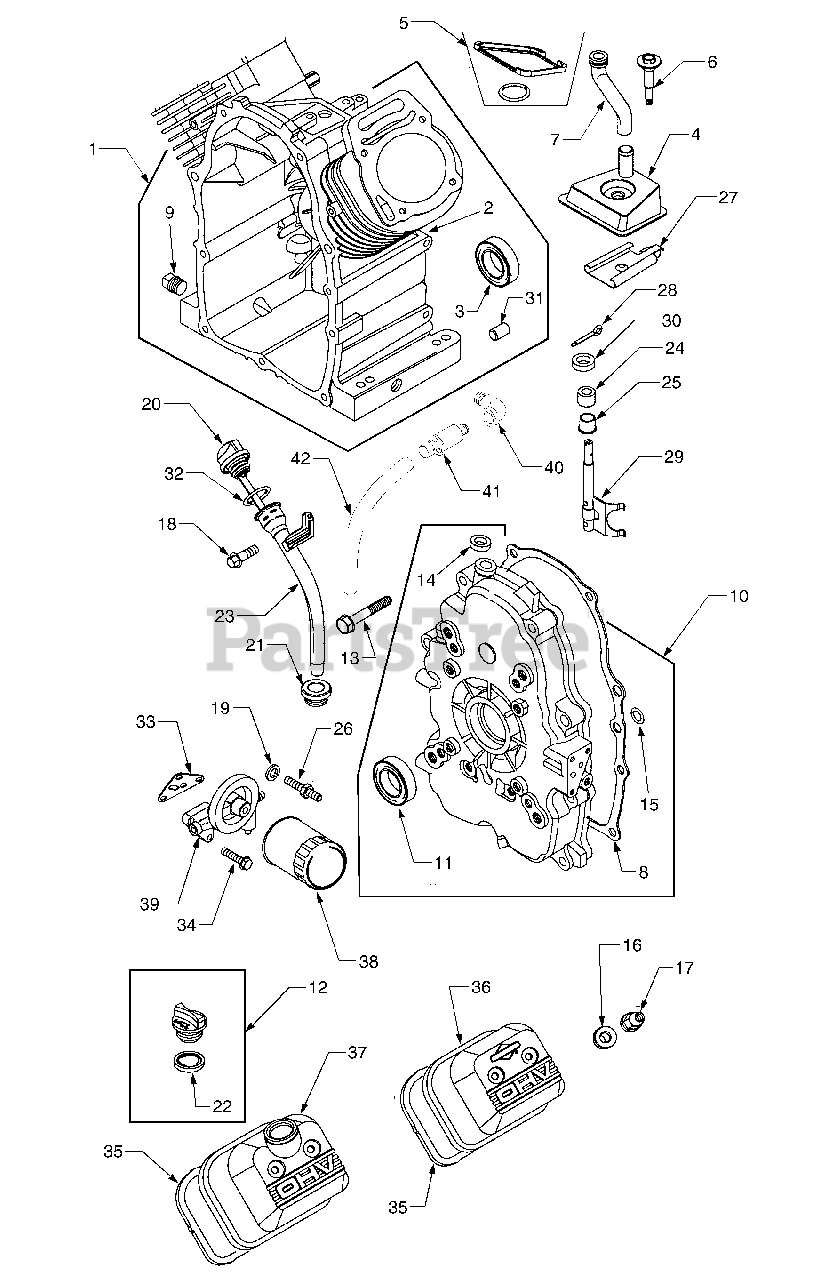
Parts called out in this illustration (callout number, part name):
1	Cylinder Assembly
2	Bearing, Cylinder
3	Seal, Oil
4	Breather Assembly
5	Gasket, Breather
6	Screw, Hex
7	Tube, Breather
8	Gasket, Crankcase Cover
9	Plug, Oil Drain
10	Cover, Crankcase
11	Seal, Oil
12	Plug, Oil Fill
13	Screw, Crankcase Cover Mtg.
14	Seal, Governor Shaft
15	Seal, O-Ring
16	Washer
17	Nut, Nylock
18	Screw, Hex
19	Washer, Lock
20	Cap and Dipstick - Oil Fill
21	Seal, Fill Tube
22	Seal, Fill Plug
23	Tube, Oil Fill
24	Bushing, Governor Shaft
25	Bushing, Governor Shaft
26	Stud, Oil Filter Adapter
27	Baffle, Breather
28	Pin, Cotter
29	Crank, Governor
30	Washer, Governor Shaft
31	Dowel Crankcase
32	Seal, O-Ring
33	Gasket, Filter Adapter
34	Screw, Hex
35	Gasket, Rocker Cover
36	Cover, Rocker
37	Cover, Rocker
38	Filter, Oil
39	Adapter, Filter
40	Elbow, 90 Degree
41	Drain, Oil
42	Hose, Oil Drain
